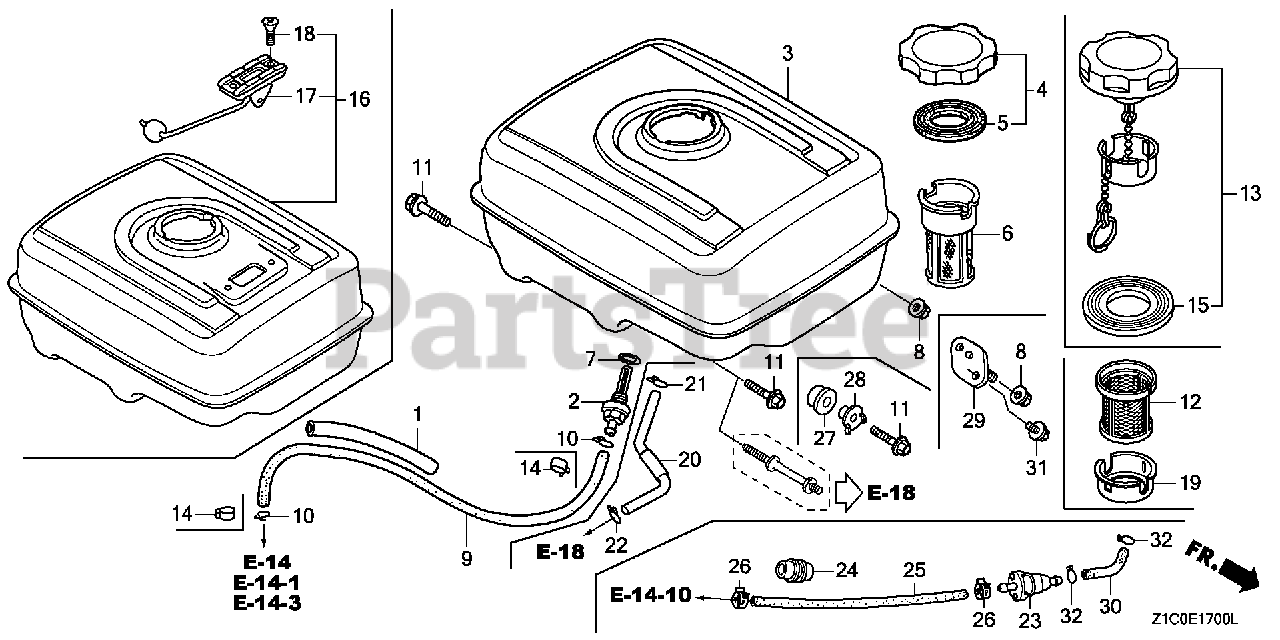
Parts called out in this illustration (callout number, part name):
1	RUBBER, SUPPORTER (107MM)
2	JOINT, FUEL TANK (NOT AVAILABLE)
2	JOINT, FUEL TANK
3	TANK, FUEL *NH31* (MCKINLEY WHITE)
3	TANK, FUEL *NH1* (BLACK)
4	CAP, FUEL FILLER (CHROME PLATED)(RADICON)
5	GASKET, FUEL FILLER CAP
6	FILTER, FUEL
7	O-RING (14MM) (ARAI) Use up to Engine SN 2949254.
7	O-RING (14MM) (NOK)
8	NUT, FLANGE (8MM)
9	BULK HOSE, FUEL (4.5X3000) (Honda Code 5137104). (4.5X140)
10	CLIP, TUBE (B8)
11	BOLT, FLANGE (8X25)
